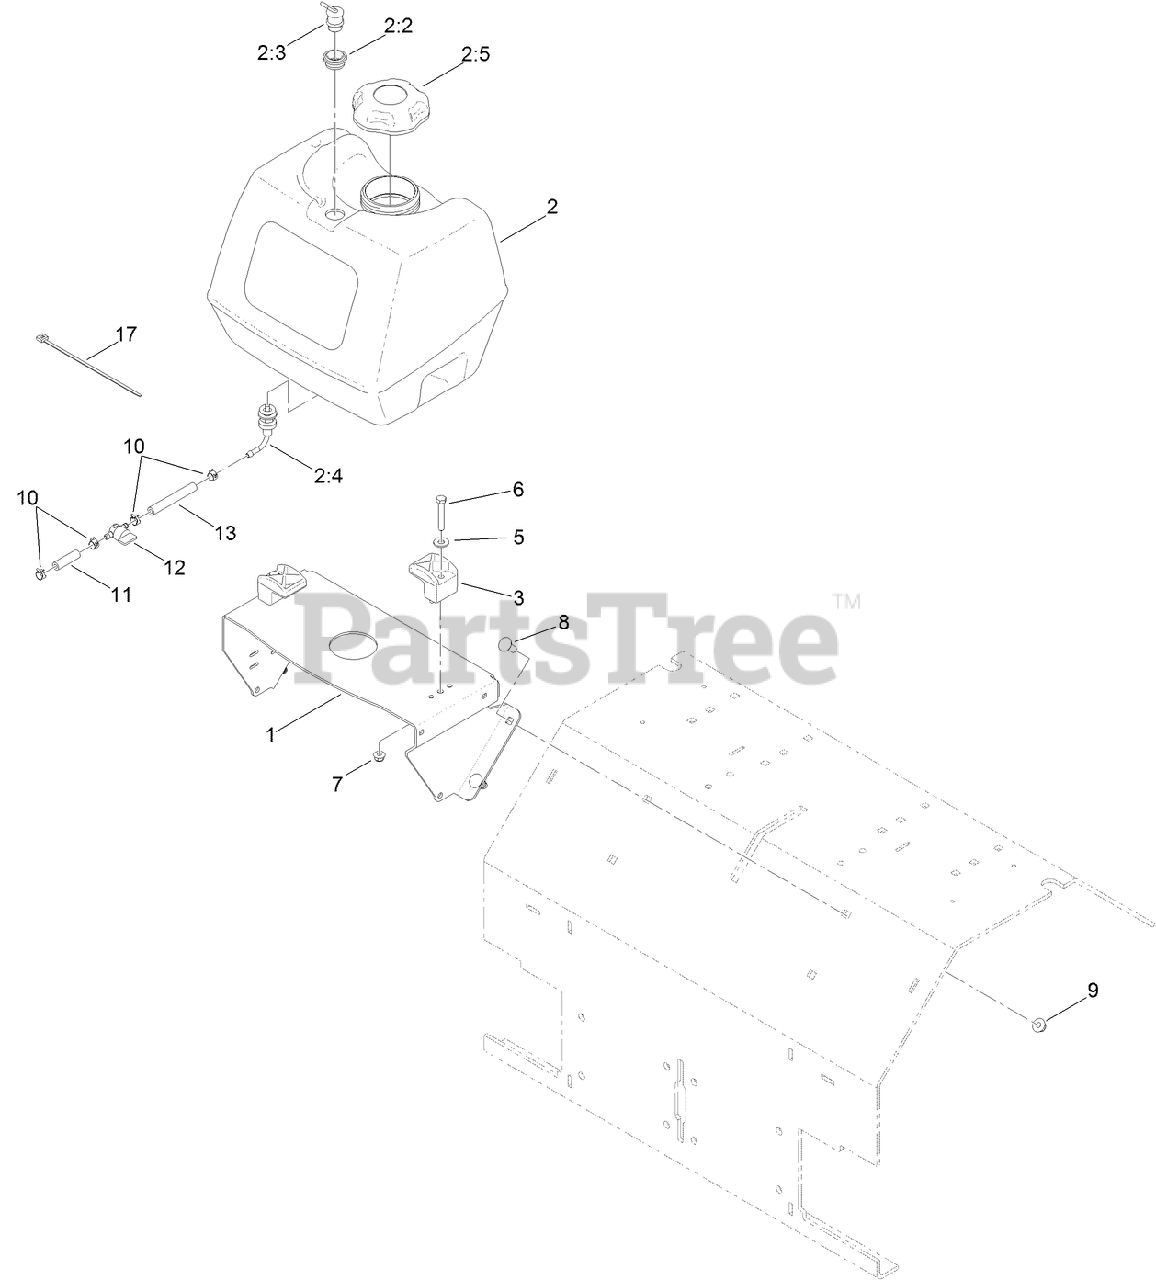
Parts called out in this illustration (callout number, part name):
1	SUPPORT-TANK, FUEL
2	FUEL TANK ASM
2:2	GROMMET
2:3	VALVE-VENT, FUEL
2:4	FITTING-FUEL, BULKHEAD
2:5	CAP-FUEL, RATCHETING
5	WASHER-FLAT
6	SCREW-HH
7	NUT-HF, NI
8	SCREW-CARR
9	NUT-HF, NI
10	CLAMP-HOSE
11	HOSE-FUEL
12	VALVE-FUEL
13	HOSE-FUEL
17	TIE-PLASTIC
